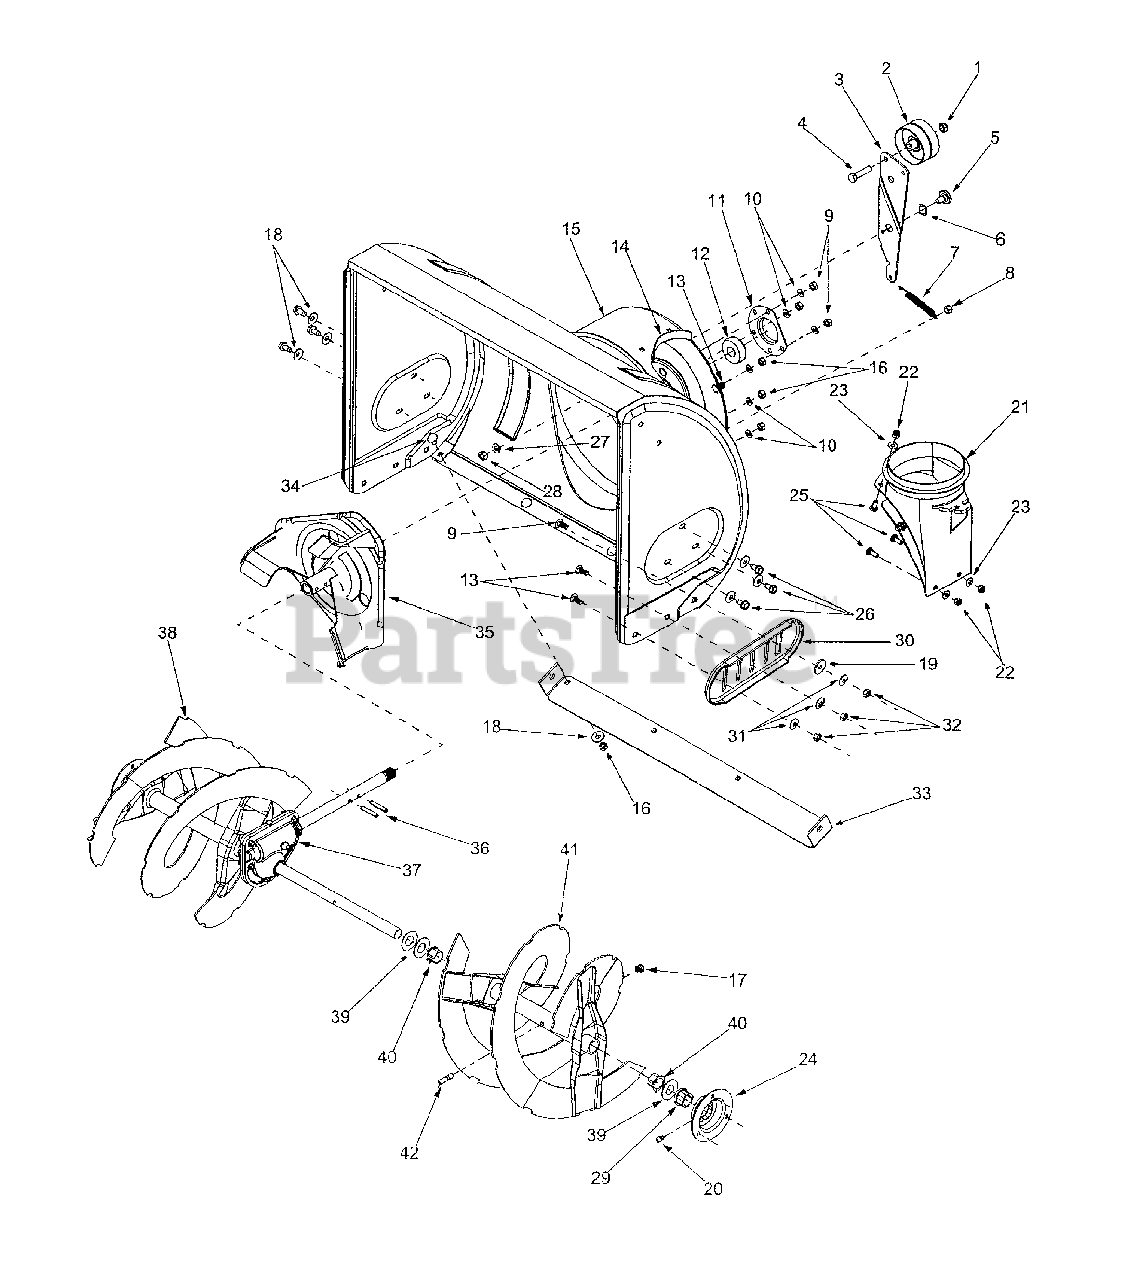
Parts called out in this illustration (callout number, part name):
1	Lock Jam Nut 3/8-24
2	Flat Idler
4	Hex Cap Screw 3/8-24 x 1.50
5	Shoulder Screw
6	Wave Washer
7	Extension Spring
8	Hex Nut 5/16-18
9	Carriage Bolt, 5/16-18 x 1.00
10	Lock Washer 5/16
12	Ball Bearing
13	Carriage Bolt, 5/16-18 x .75
17	Lock Nut 5/16-18
18	Belleville Washer
19	Flat Wshr, .344ID x 1.125 OD
20	Grease Fitting, 3/16" Drive
21	Chute Adapter
22	Hex Lock Nut 1/4-20
23	Flat Washer
24	Bearing Housing w/Fitting
25	Carriage Screw 1/4-20 x .75
26	Hex Screw 5/16-18
27	Lock Washer 3/8
28	Hex Nut 3/8-16
29	Hex Flange Bearing
31	Bell Washer
32	Hex Nut 5/16-18
34	Carriage Bolt 5/16-18 x .62
37	26" Gear Ass'y
39	Flat Washer
40	Flange Bushing
